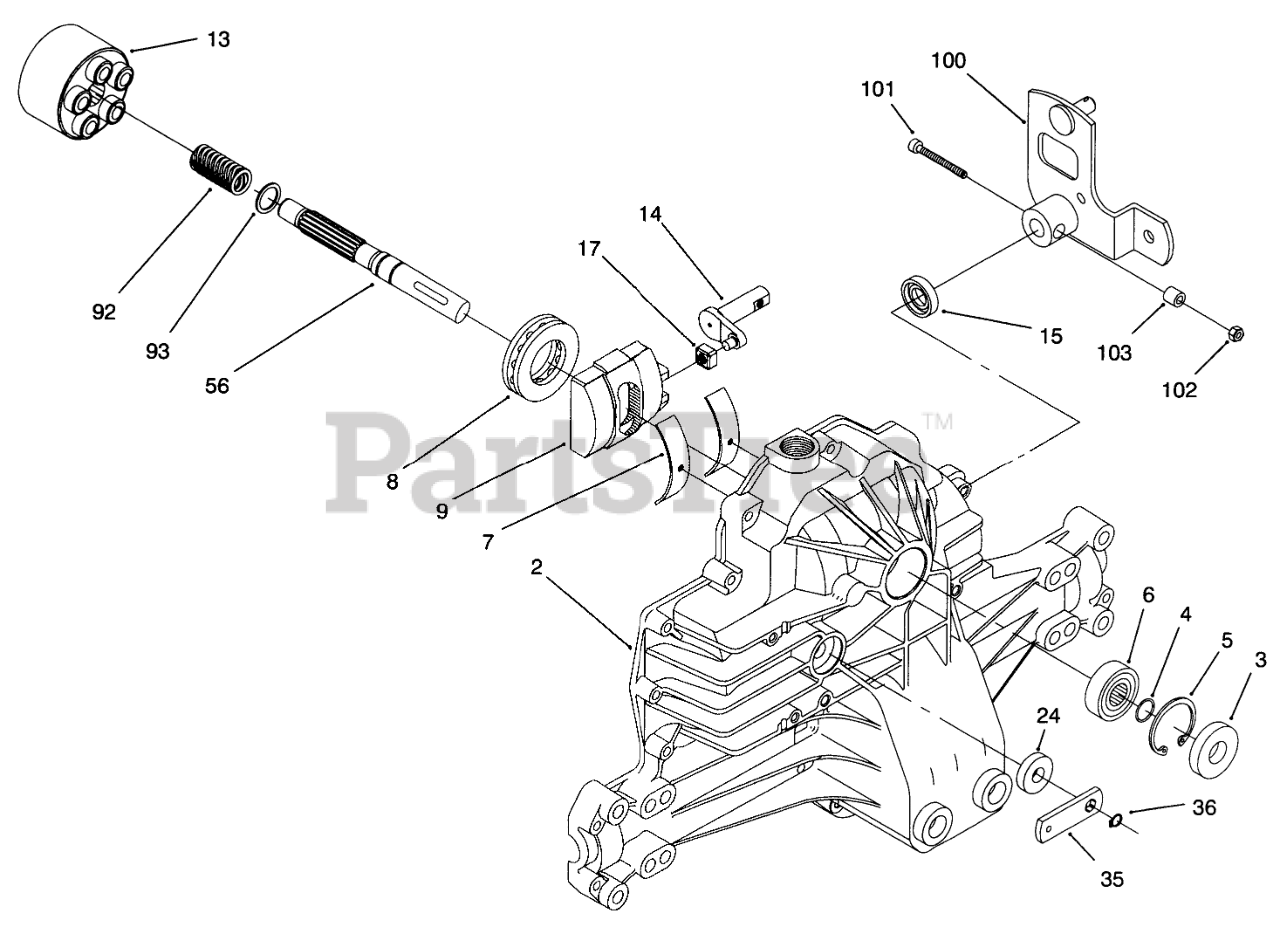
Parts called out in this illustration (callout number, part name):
2	ASM - HOUSING UPPER
3	SEAL-LIP
4	RING-WIRE, RETAINING
5	RING-RETAINING
6	BEARING-SHAFT, BALL
7	BEARING-CRADLE
8	BEARING-THRUST
9	SWASHPLATE-VARIABLE
13	BLOCK - CYCLINDER ASM
14	ARM-TRUNION
15	SEAL-LIP
17	GUIDE-SLOT
24	SEAL-LIP
28	RING - RETAINING
35	ARM - BYPASS
36	RING-RETAINING
56	SHAFT - INPUT
92	SPRING-BLOCK
93	WASHER-THRUST
100	WA - SPEED CONTROL LEVER
101	SCREW-HSH
102	NUT-LOCK, NI
103	LOCK SPACER
